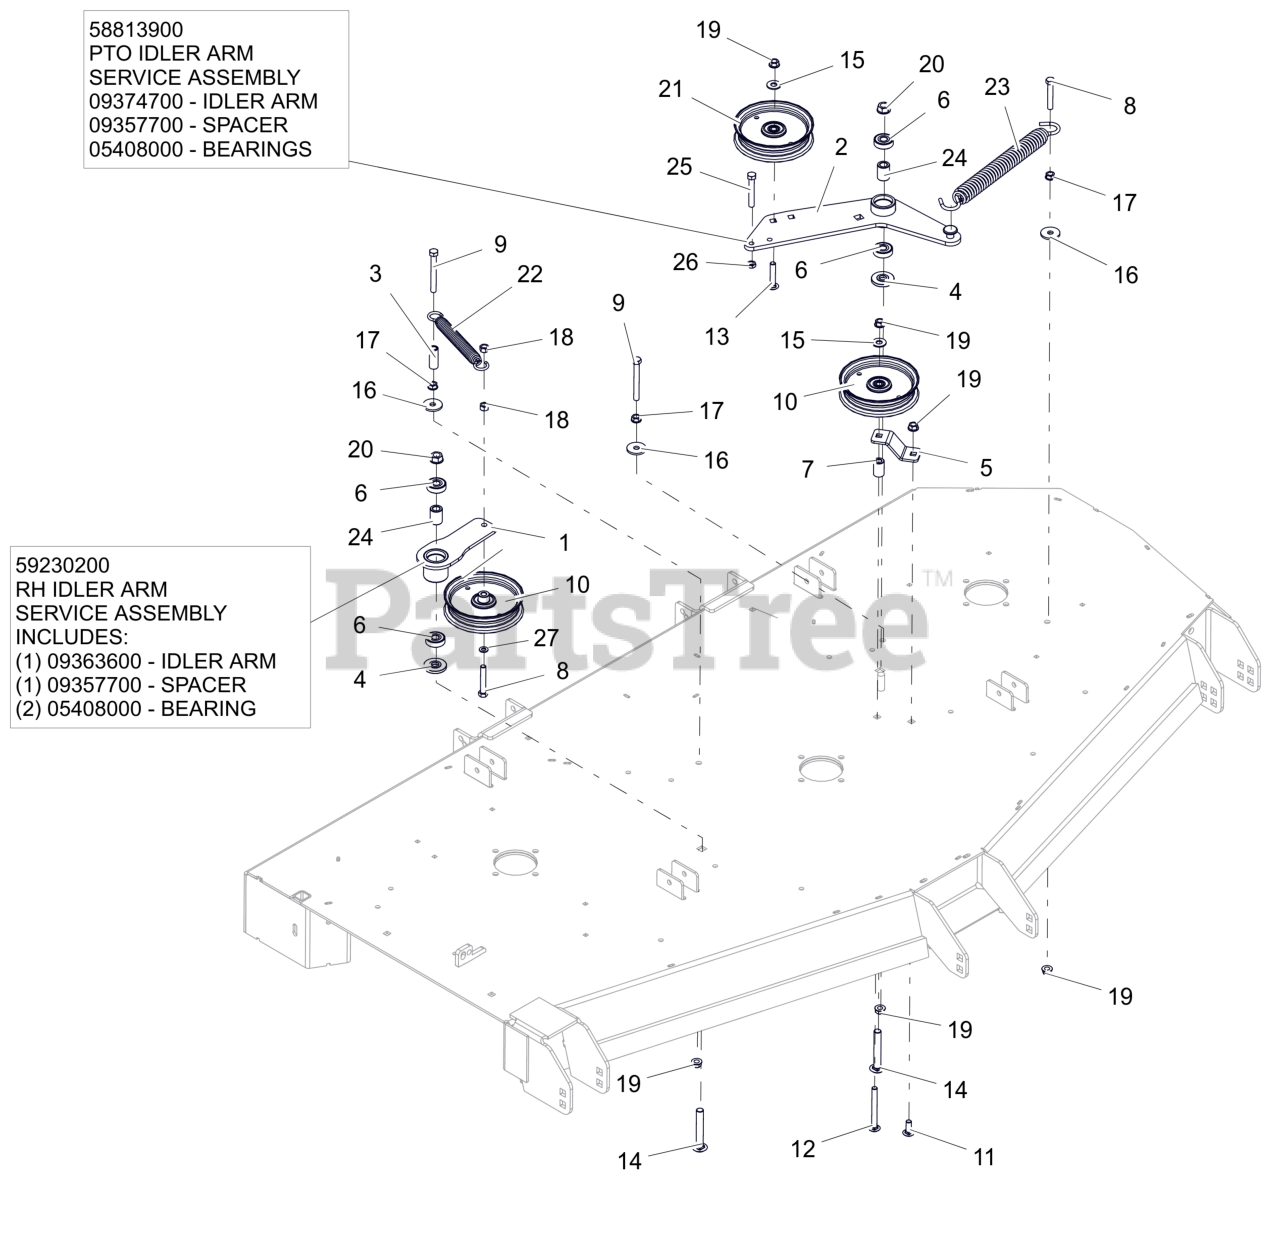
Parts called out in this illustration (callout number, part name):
1	WLDMT, DECK RH IDLER ARM
1	PTO IDLER ARM
1	SPACER .510 X .867 X 1.1485
1	BRG-BALL .500X1.38X.437
2	WLDMT, IDLER ARM PT660
2	RH IDLER ARM
2	SPACER .510 X .867 X 1.1485
2	BRG-BALL .500X1.38X.437
3	SPACER, .375IDX.625ODX1.66 PM
4	SPACER, IDLER ARM
5	PTO FIXED IDLER MTG BRKT -RED
6	BRG-BALL .500X1.38X.437
7	BUSHING, SLV .380X.750X1.190
8	BLT,HEX .38-16X2.25 G5 ZCC
9	BLT, HEX .38-16X3.25 G5 ZCC
10	IDLER- FLAT - 5.00" X .75"
11	BLT,RHSSN .38-16X1.00 G5 ZCC
12	BLT,RHSSN .38-16X3.50 G5 ZCC
13	BLT,RHSSN.375-16X2.00 G5 ZCC
14	BTL,RHSSN .500-13 X 3.25 G5 ZCC
15	WSHR,FLT .438X1.00X.083 ZCC
16	WSHR,FLT .406X1.375X.135 ZCC
17	NUT, SPNLK-FLG .38-16 G5 ZCC
18	NUT-LK-CTR .38-16 ZC120
19	NUT-LK-CTR-FLG .375-16 GF ZCC
20	NUT-LK-CTR-FLG .500-13 GG ZCC
21	PULLEY, FLAT IDLER .500 X .375 W/BRG
22	SPRING- EXTENSION
23	SPRING, EXTENSION
24	SPACER .510 X .867 X 1.1485
25	BLT, HEX .38-16X2.50 G5 ZCC
26	NUT-JAM .375-16 G2 ZCC
27	WSHR,FLT .323X.625X.062 ZCC
